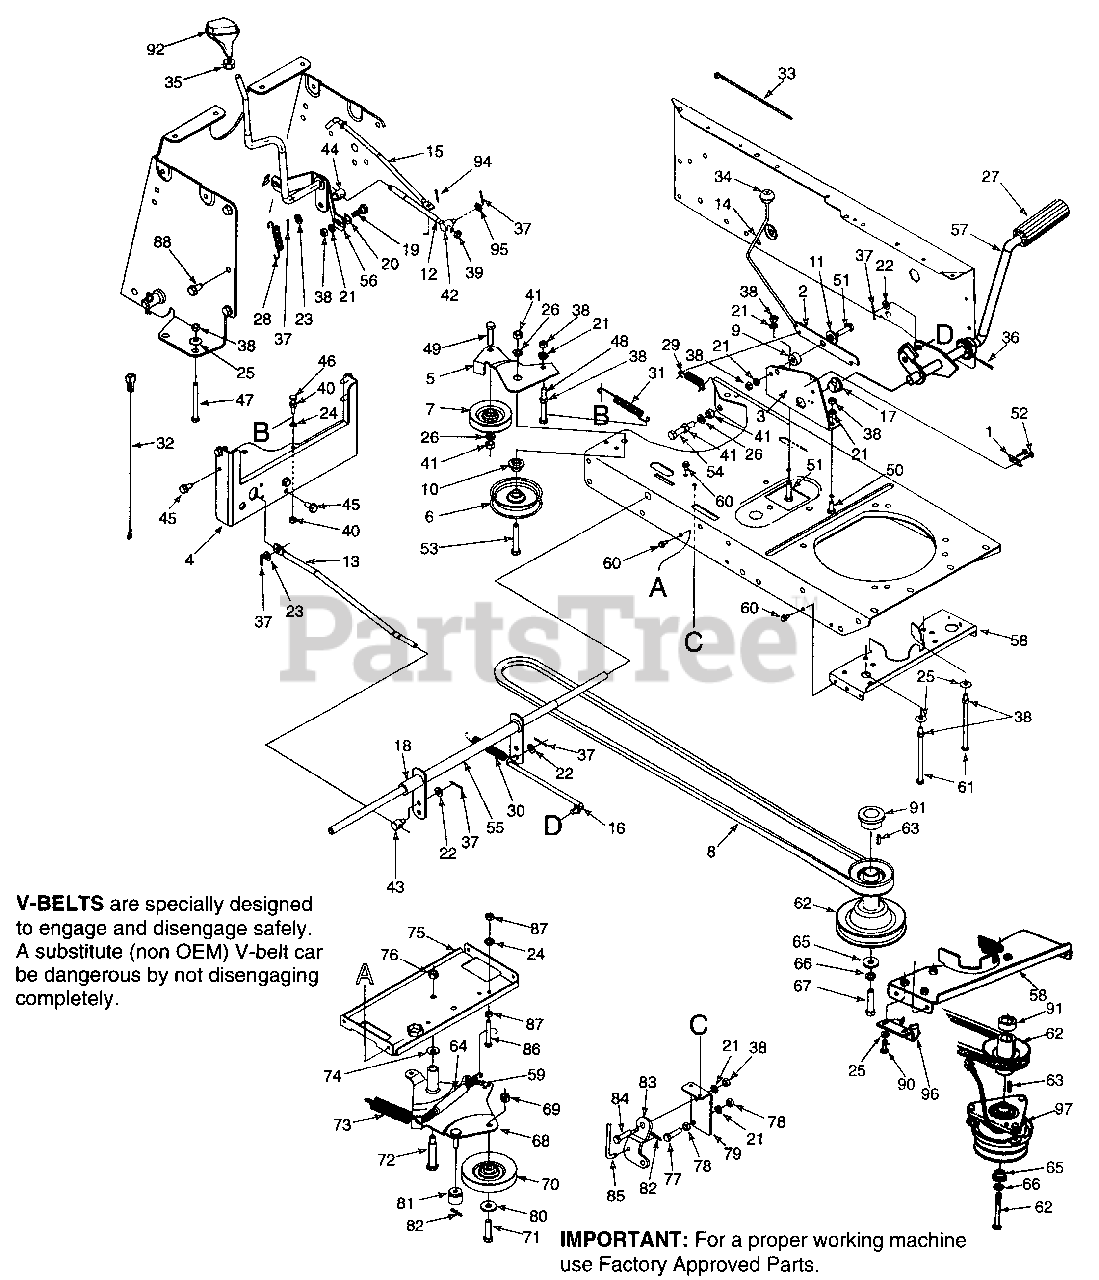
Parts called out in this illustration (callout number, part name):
1	Switch Plate
7	Idler Pulley
8	"V"-Belt
9	Spacer .34" I.D. x .44" Lg.
10	Shld. Spacer .38" I.D.
11	Shld. Spacer
12	Speed Selector Rod
13	Neutral Return Rod
14	Brake Lockout Rod
15	Hydro Disengagement Rod
16	Brake Link Rod
17	Hex Flange Bearing
18	Nyliner Flange Bearing
19	Shld. Bolt
20	Spr. Wash. 7/16" I.D.
21	L-Wash. 5/16" I.D.
22	Fl-Wash. 5/16" I.D.
23	Fl-Wash. .38" I.D.
24	L-Wash. 1/4" I.D.
25	Bell-Wash. .345" I.D.
26	L-Wash. 3/8" I.D.
27	Foot Pad
28	Ext. Spring 2.75" Lg.
29	Ext. Spring 2.51" Lg.
30	Ext. Spring 4.74" Lg.
31	Ext. Spring 4.97" Lg.
32	Transmission Wire
33	Cable Tie
34	Ball Knob
35	Hex Jam Nut 3/8-16 Thd. (Gr. 5)
36	Cotter Pin 1/8" Dia. x 1" Lg.
37	Cotter Pin 3/32" Dia. x 1" Lg.
38	Hex Nut 5/16-18 Thd. (Gr. 5)
39	Hex Jam Nut 5/16 Thd. L.H.
40	Hex Nut 1/4-20 Thd. (Gr. 5)
41	Hex Nut 3/8-16 Thd. (Gr. 5)
42	Ferrule 5/16-24 Thd. L.H.
43	Ferrule 5/16-18 Thd.
44	Ferrule 3/8-24 Thd.
45	Hex Wash. TT-Tap Scr. 5/16 x .75" Lg.
46	Hex Bolt 1/4-20 x 1.25" Lg.
47	Hex Bolt 5/16-18 x 3" Lg.
48	Hex Bolt 5/16-18 x 2.75" Lg.
49	Hex Bolt 3/8-16 x 1.5" Lg.
50	Hex Bolt 5/16-18 x .75" Lg.
51	Hex Bolt 5/16-18 x 1.25" Lg.
52	Hex HD Tapp Scr. #10-16 x .75" Lg.
53	Hex Bolt 3/8-16 x 2.25" Lg.
54	Hex Bolt 3/8-16 x 2" Lg. (Gr. 5)
57	Hydro Foot Pedal Ass'y.
60	Hex Wash. TT-Tap Scr. 1/4-20 x.5"
61	Hex Bolt 5/16-18 x 5.25" Lg.
62	Engine Pulley
63	Sq. Key 1/4 x 1.5" Lg.
64	Convoluted Conduit
65	Fl-Wash. .45" I.D. x 1.25"
66	L-Wash. 7/16" I.D.
67	Hex Bolt 7/16-20 x 1.5" Lg.
68	Idler Brkt. Deck Ass'y.
69	Hex Cent. L-Nut 3/8-24 Thd.
70	Idler Pulley
71	Hex Bolt 3/8-24 x 1.5" Lg.
72	Shld. Bolt .498" Dia. x 2.05"
73	Ext. Spring 6.12" Lg.
74	Bell-Wash. .38" I.D. x .88" O.D.
76	Hex Cent. L-Nut 3/8-16 Thd.
77	Hex Bolt 5/16-24 x 1.25" Lg.
78	Hex Nut 5/16-24 Thd. (Gr. 5)
79	Parking Brake Mtg. Brkt.
80	Fl-Wash. .40" I.D. x .875" O.D.
81	Spacer
82	Hairpin Clip
83	Deck Control Pivot Brkt.
84	Shld. Bolt .437" Dia. x .162"
85	Deck Control Rod
86	Hex Bolt 1/4-20 x 2" Lg.
87	Hex Nut 1/4-20 Thd.
88	Hex AB-Tap Scr. 5/16 x .75"
90	Hex Bolt 5/16-18 x .75" Lg.
91	Clutch Spacer
92	Shift Knob
94	Hairpin Clip
95	Fl-Wash. .344" I.D. x .75" O.D.
